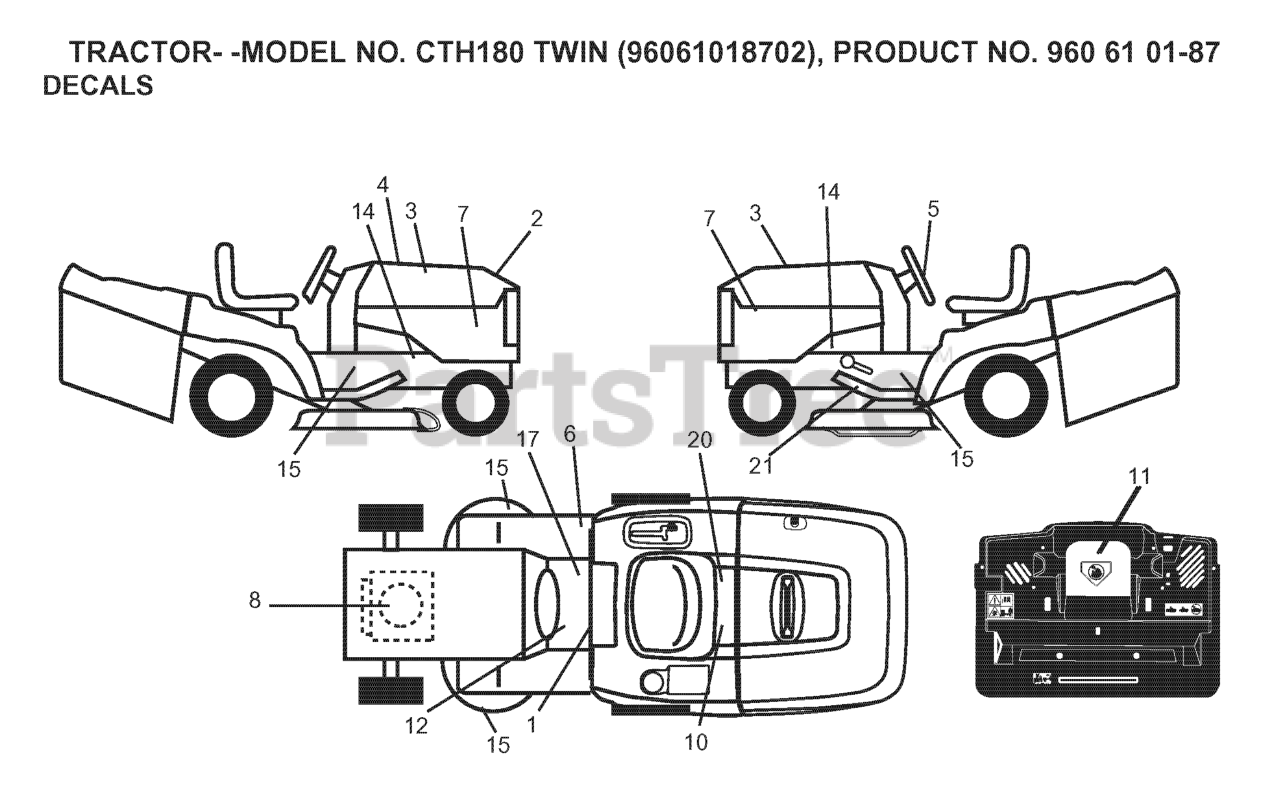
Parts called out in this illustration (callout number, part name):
1	LABEL
2	DECAL.HOOD.TOP.INSERT.
3	DECAL.HOOD.NAMELOGO.HUSQ
5	DECAL.WHEEL.STRG.LGN.H
6	Decal, Fender 100 DB/CE
8	DECAL
10	DECAL BTRY SYMBOLS
11	DECAL.INTERNATIONL.CUTFINGER
12	DECAL
17	DECAL PARK BRAKE
20	DECAL.BYPASS.FENDER.CRD.LT.YT
